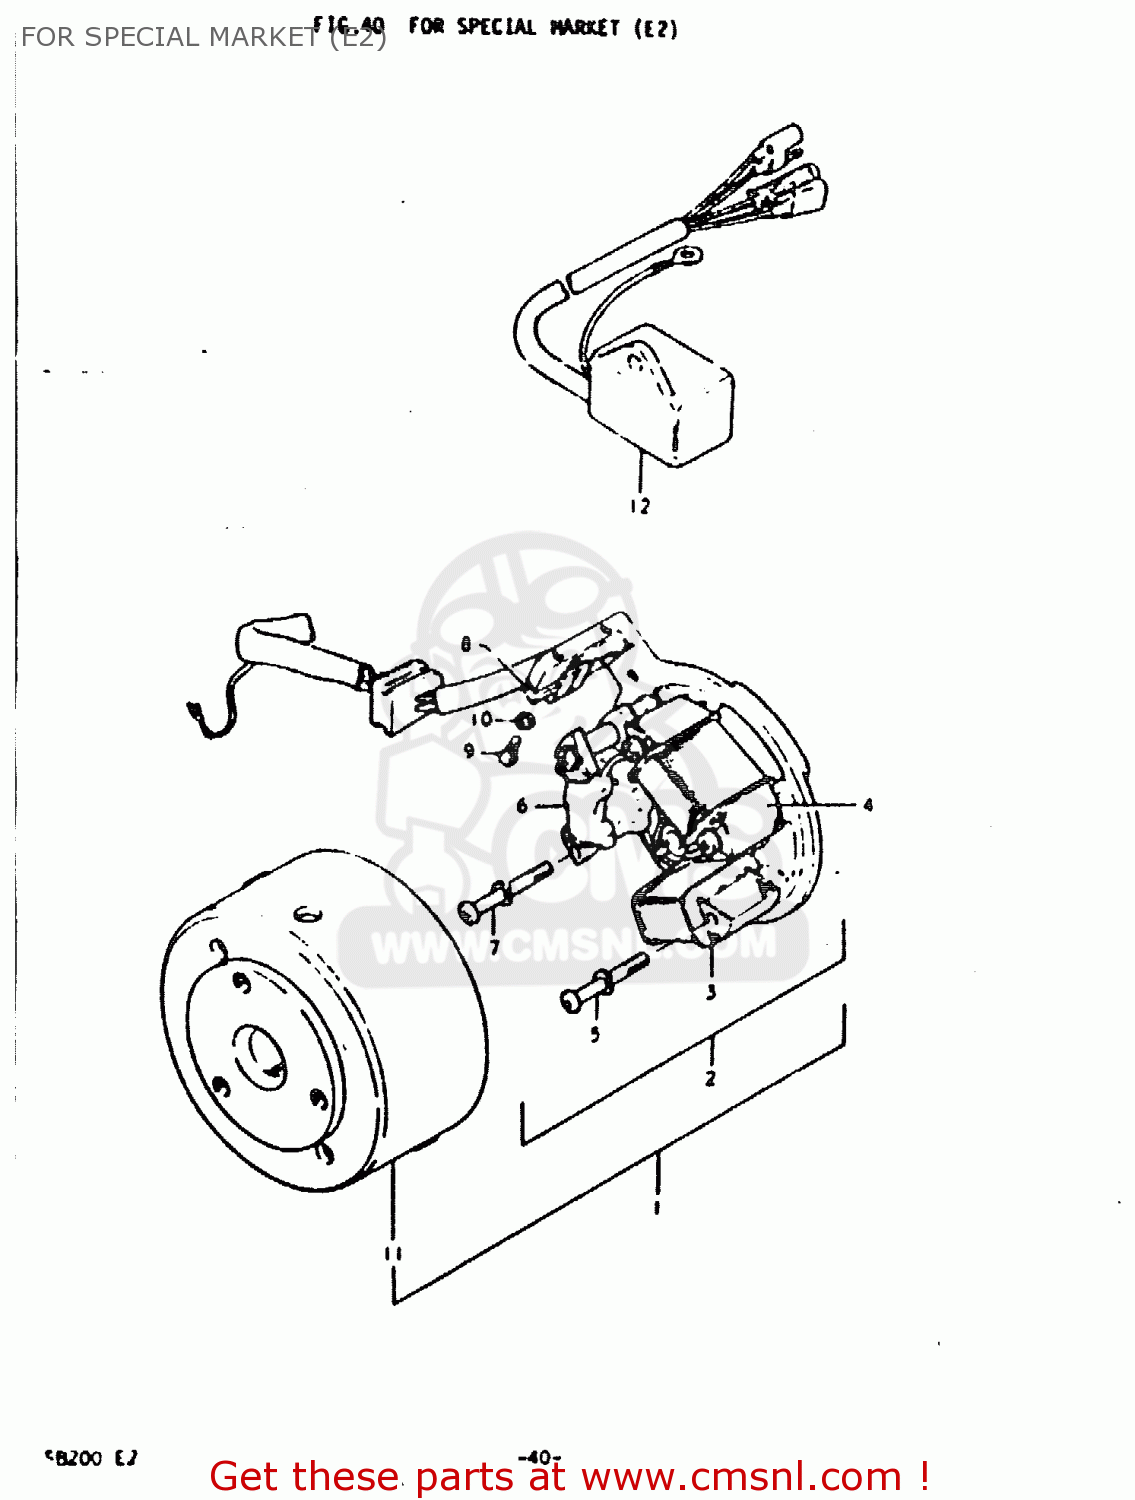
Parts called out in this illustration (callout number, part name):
1	MAGNETO ASSY
2	STATOR ASSY
3	COIL,LIGHTING(A)
4	COIL, LIGHTING B
5	SCREW
6	COIL, PRINAR,
7	SCREW
8	COIL,PULSER
9	SCREW
10	LOCK WASHER
11	ROTOR
12	C.D.I. UNIT ASSY
